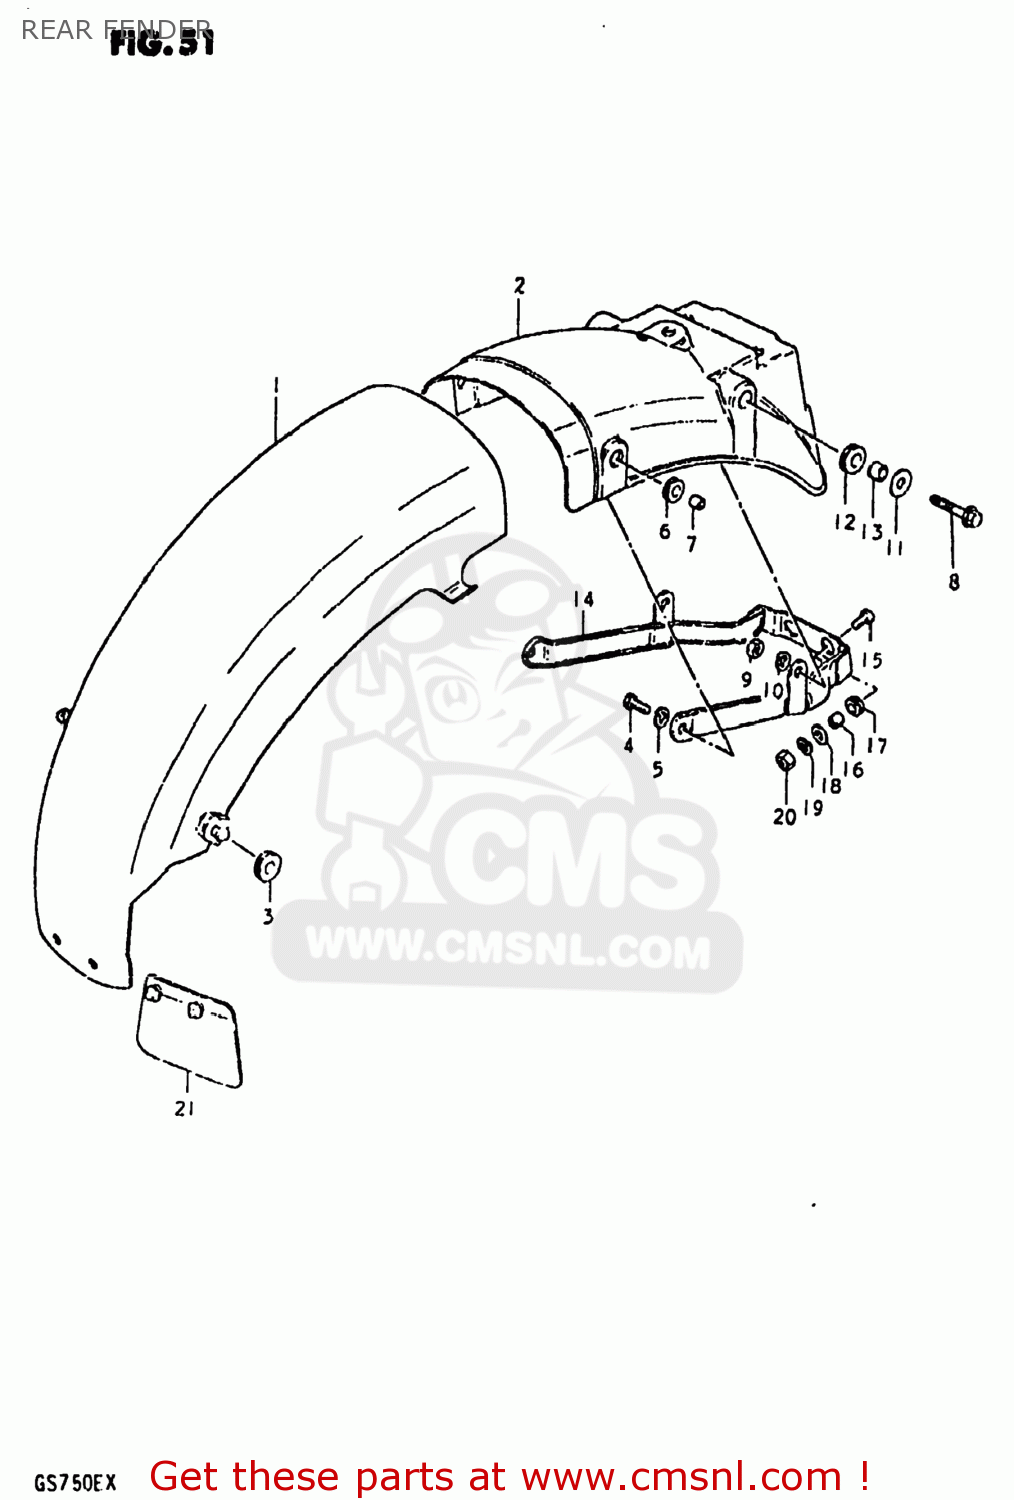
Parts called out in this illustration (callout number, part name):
1	FENDER,REAR
2	BODY,REAR FENDER,REAR
3	CUSHION
4	BOLT
5	LOCK WASHER
6	CUSHION
7	SPACER(6.1X9X7.5)
8	BOLT
9	NUT
10	LOCK WASHER
11	WASHER(8.5X26X1.2)
12	CUSHION
13	SPACER (8.2X12X7.5)
14	REINFORCEMENT,REAR FENDER
15	SCREW
16	SPACER (6.1X9X9)
17	CUSHION
18	WASHER(6,5X22X1.6)
19	LOCK WASHER
20	NUT
21	GUIDE,RR FENDER MUD
